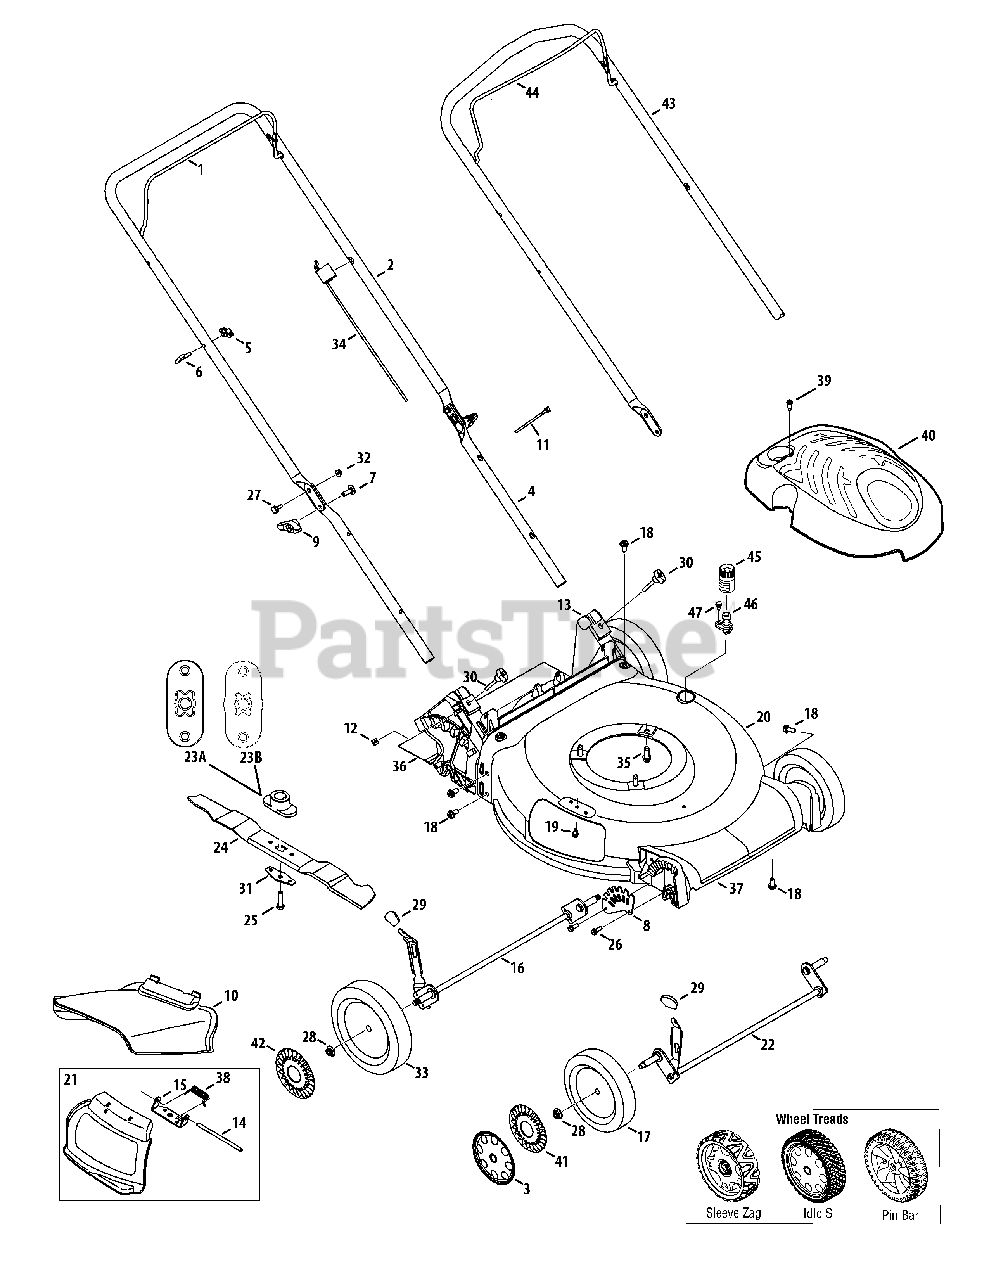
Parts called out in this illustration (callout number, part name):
1	Blade Control Handle - Black
2	Upper Handle - Black (adjustable)
3	Hub Cap (7")
4	Lower Handle
5	Knob 1/4-20
6	Rope Guide Bolt
7	Carriage Bolt 5/16-18
8	Front Height Adjustment Plate
9	Wing Knob 5/16-18 Black
10	Chute Deflector
11	Cable Tie
12	Sq. Nut 1/4-20
13	Rear Baffle
14	Hinge Pin
15	Chute Deflector Bracket
16	Rear Axle Ass'y - 8" wheel
17	Wheel Ass'y 7 x 2.0 Sleeve Zag Black
18	Hex Hd. Cap Screw 5/16-14 x .75
19	Sems TT Screw 1/4-20 x .50
20	21" Deck Ass’y
21	Hinged Mulch Plug Ass'y (Incl. ref. no.15, 38 & 14)
22	Front Axle Ass'y - 7 " wheel
23B	Blade Adapter (25 mm x 1.19)
24	21" Mulching Blade
25	Hex Bolt 3/8-24 x 1.5" Lg. (Gr 8)
26	Screw, 1/4-15 x .750
27	Shoulder Screw .375 x .126 x 1/4-20
28	Flange Locknut 3/8-16 Gr. F Nylon
29	Knob (Black)
30	Knob 1/4-20 x 1.725 Black
31	Blade Bell Support
32	Flanged Lock Nut 1/4-20 Gr. F Nylon
33	Wheel Ass'y 8 x 2.125 Sleeve Zag Black
34	Control Cable, 160 cc Honda
35	Hex Wash HD Tap Scr 3/8-16 x .88
36	Trailing Shield 4.54 x 17.37
37	Front Axle Cover
38	Torsion Spring
39	Screw, HL, #12-16 x 1.0
40	En gine Shroud M1.1 Black
41	Hub Cap (7")
42	Hub Cap (8")
43	Upper Handle (Ergo)
44	Blade Control Handle
45	Water Nozzle Adapter
46	Deck Water Nozzle
47	Shoulder Screw 1/4-20 x .50
